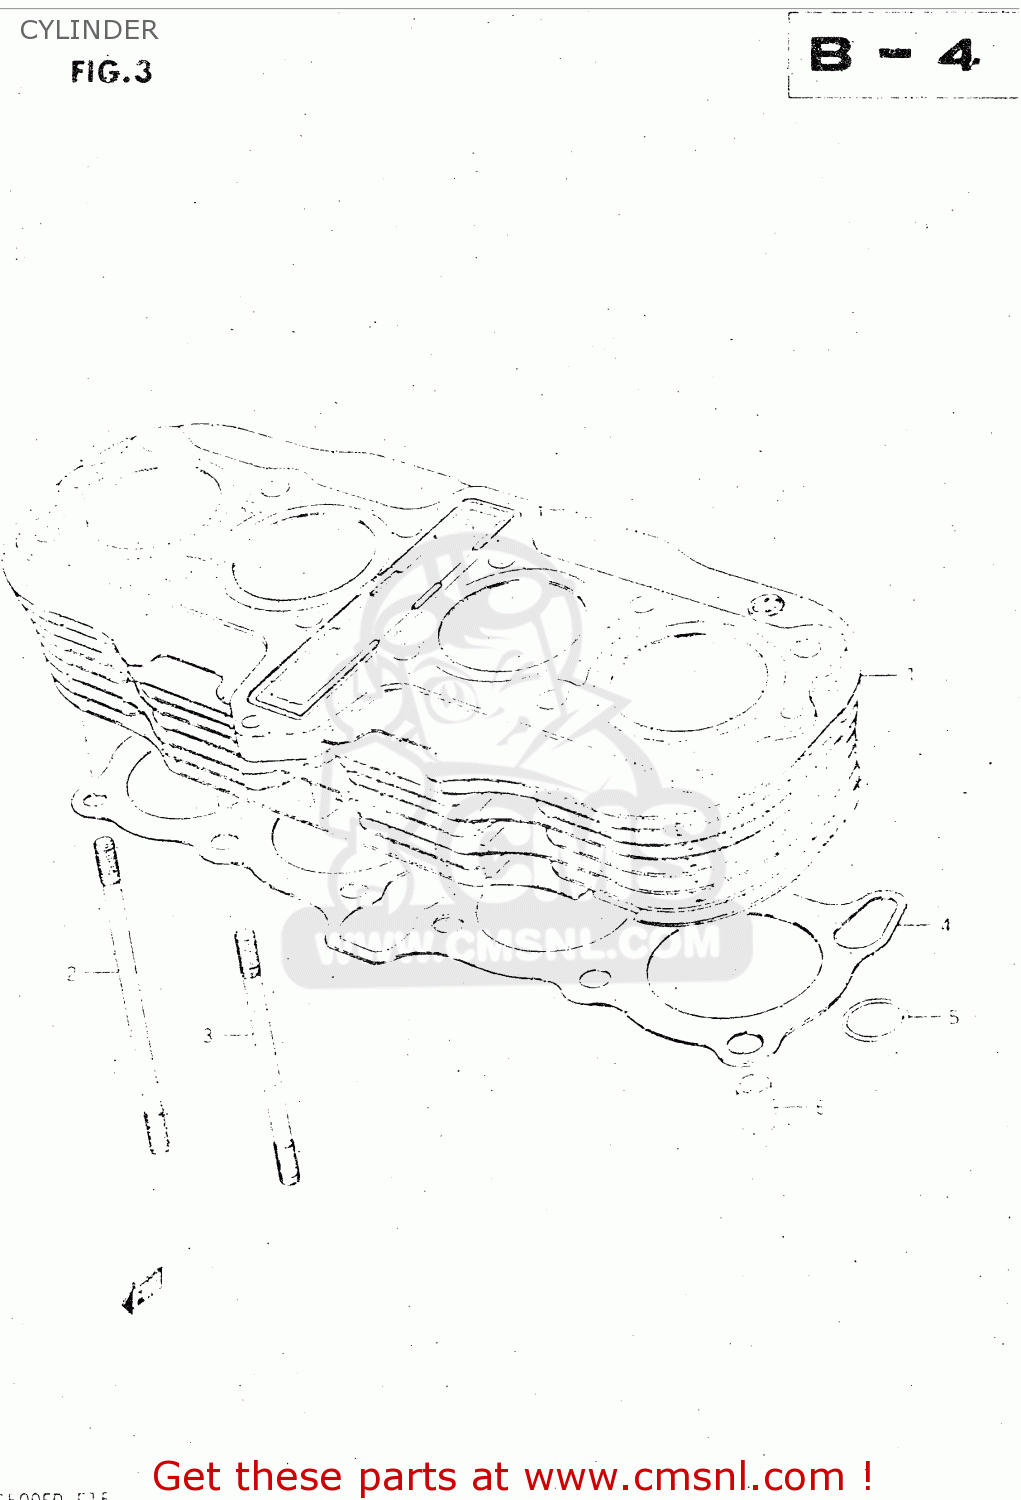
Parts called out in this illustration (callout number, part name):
1	CYLINDER
2	BOLT,STUD
3	BOLT,STUD
4	GASKET,CYLINDER (MCA)
5	INVALID PARTNUMBER
6	PIN
